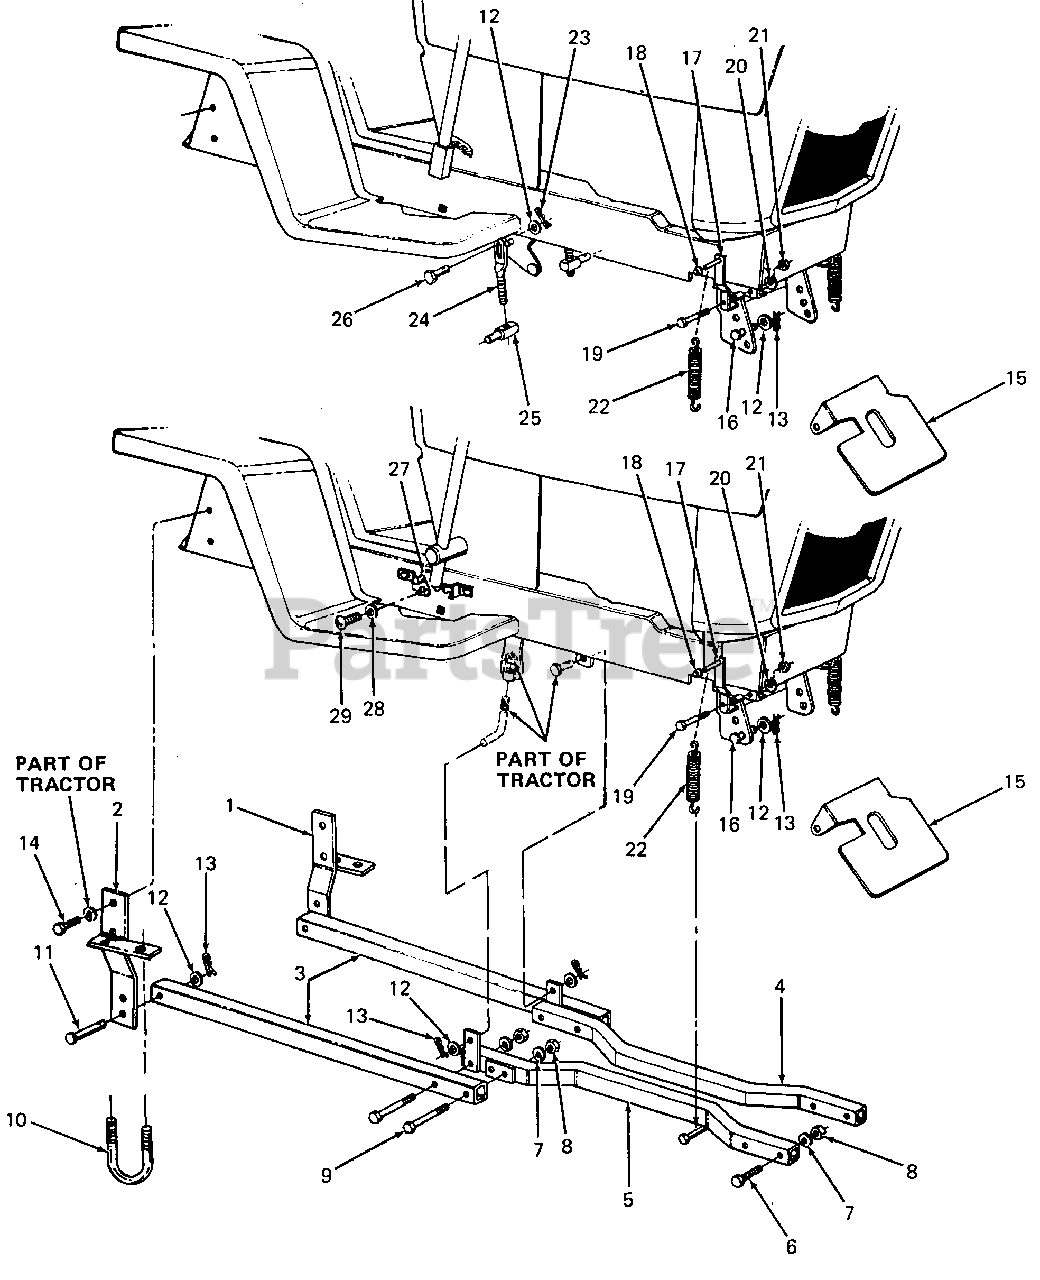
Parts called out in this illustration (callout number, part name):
1	Hanger, LH - Rear
2	Hanger, RH - Rear
3	Tubing, 1.5 X 1.5 X 35.0 Lg
6	Screw, Hex Cap, 1/2-13 X 2.75
7	Washer, Lock, 1/2
8	Nut, Hex, 1/2-13
9	Screw, Hex Cap, 1/2-13 X 4.0 Lg
10	U-Bolt, 5/16-18 X 2.75 Lg
11	Pin, Clevis, .50 Dia X 2.19 Lg
12	Washer, Flat, .510 X 1.0 X .060 Thk
13	Pin, Internal Cotter
14	Screw, Hex Cap, 3/8-16 X 1.25 Lg
15	Bracket, Guide
16	Pin, Clevis, .50 Dia X .40 Lg
19	Screw, Hex Cap, 1/4-28 X 1.25 Lg
20	Washer, Lock, 1/4
21	Nut, Hex, 1/4-28
22	Spring, Extension, 1.0 OD X 4.17 Lg
23	Pin, Internal Cotter
24	Link, Adjustment
25	Ferrule, Adjustment
26	Pin, Lift Bracket
27	Plate, Lift Handle Stop
28	Washer, Bell, .265 X .75 X .062 Thk
29	Screw, Truss Mach, 1/4-20 X .75 Lg
